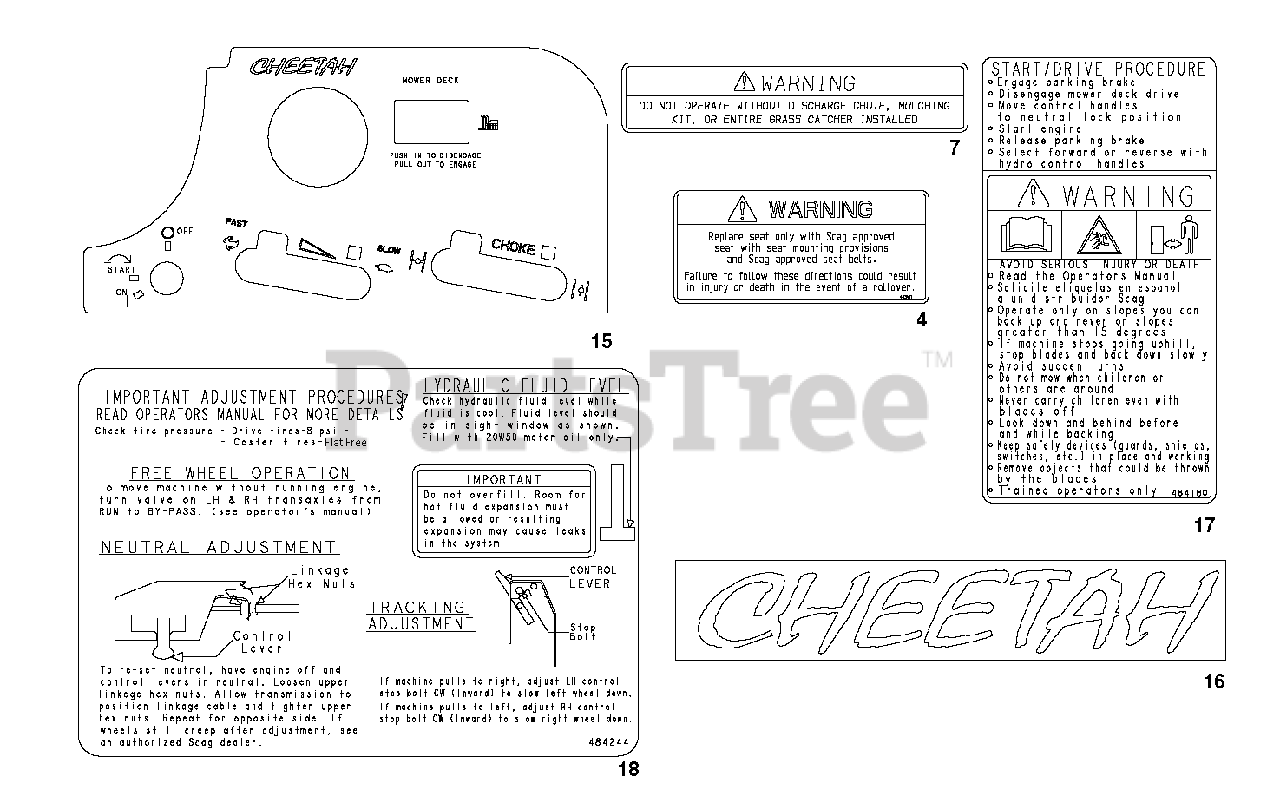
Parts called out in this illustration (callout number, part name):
4	Decal, Seat Replacement
7	Decal, Warning
15	Decal, Instrument Panel - SCZ
16	Decal, Cheetah
17	Decal, Start / Drive
18	Decal, Adjustments - SCZ
